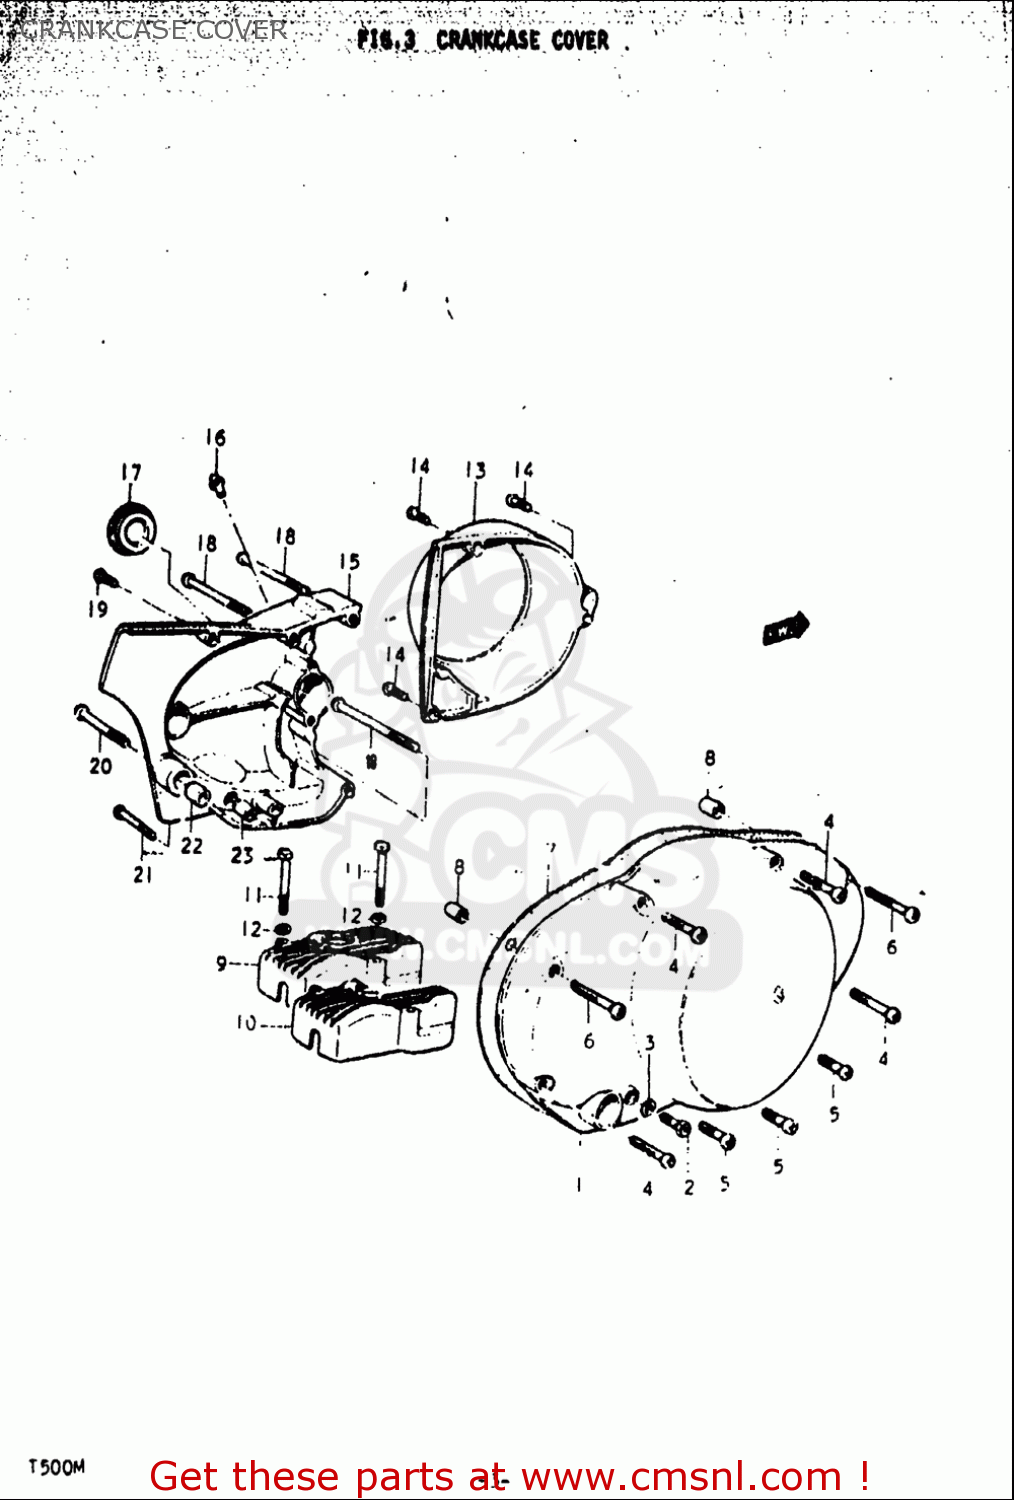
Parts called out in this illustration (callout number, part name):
2	SCREW(6X10)
3	GASKET(6.2X11X1) (NAS)
4	SCREW
5	SCREW
6	SCREW
7	GASKET,CLUTCH COVER (NAS)
8	PIN
11	BOLT(6X35)
12	WASHER
14	SCREW
16	NIPPLE
17	CAP(OD:36)
18	SCREW
19	SCREW
20	SCREW
21	SCREW
22	PIN
